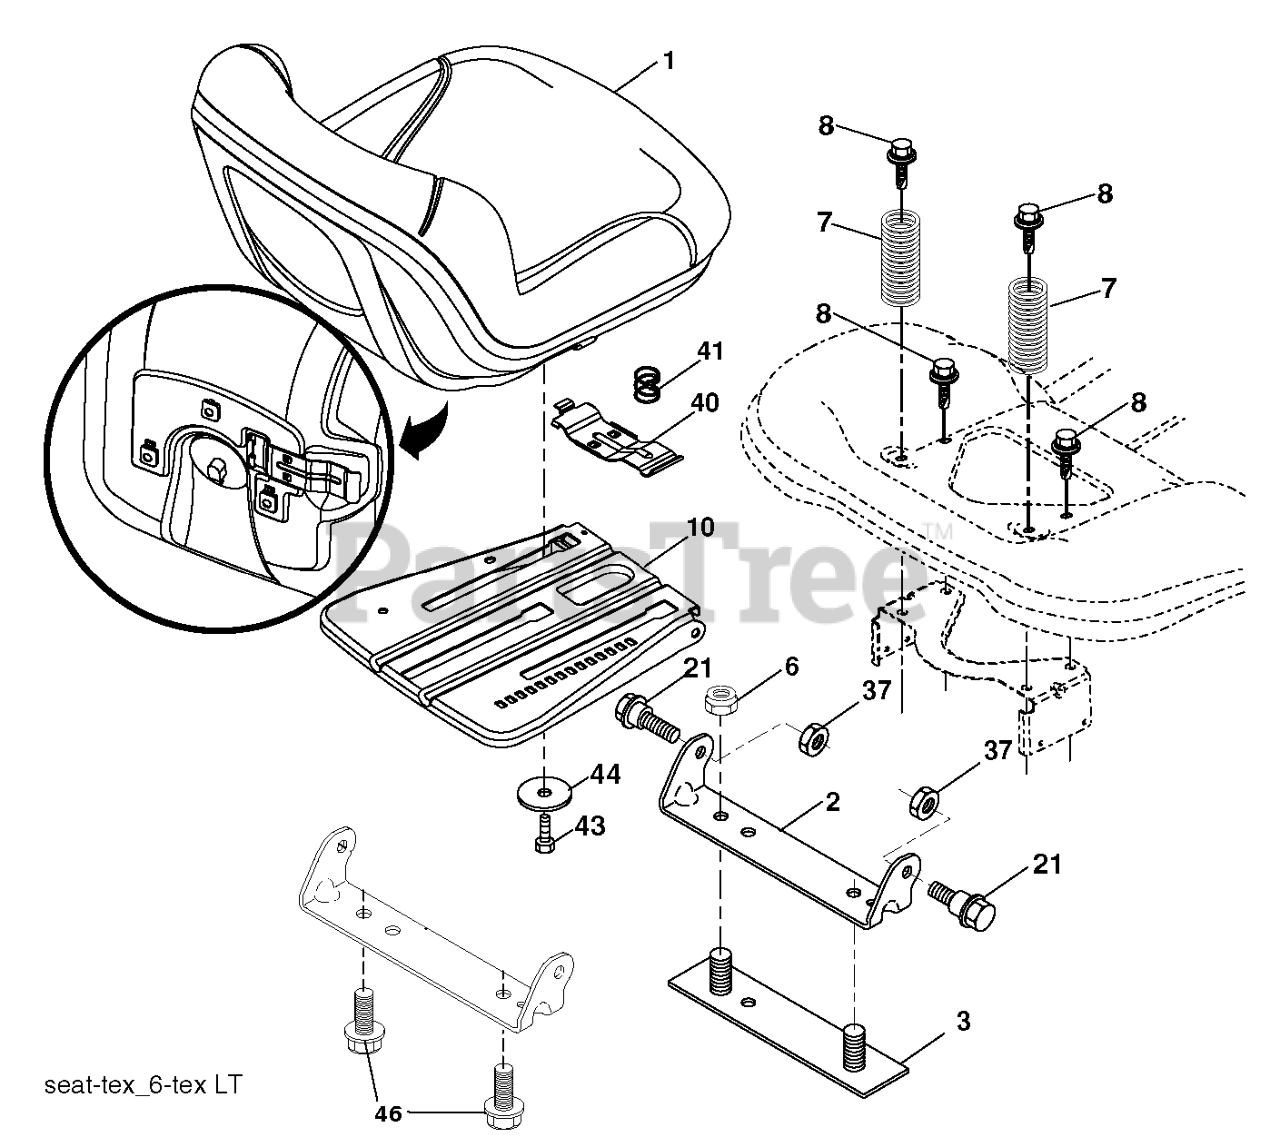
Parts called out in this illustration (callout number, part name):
1	SEAT.TH110.HUSQ.TEX.GREY
1	SEAT.TH130.GREY.HUSQ.TEX
2	BRKT.PIVOT.FENDER
3	STRAP
6	NUT
7	SPRING.COMPRESSION.SEAT.BLACK
8	BOLT.5/16-18UNCX3/4 W/SEMS.BLK
10	PAN.ASM.SEAT.3PT
21	BOLT.5/16-18X5/8.SHOULDER
37	NUT.71038.31-18.HEX.NYLOCK
40	HANDLE.SLIDE.SEAT.TEX.BLACK
41	SPRING.LATCH.SEAT.TEX
44	WASHER.WINGED.3/8ID.1.5OD
44	WASHER 13/32 X 2-3/8 X 12GA
46	BOLT.3/8-16X1;1.25OD.WSHR.SEMS
